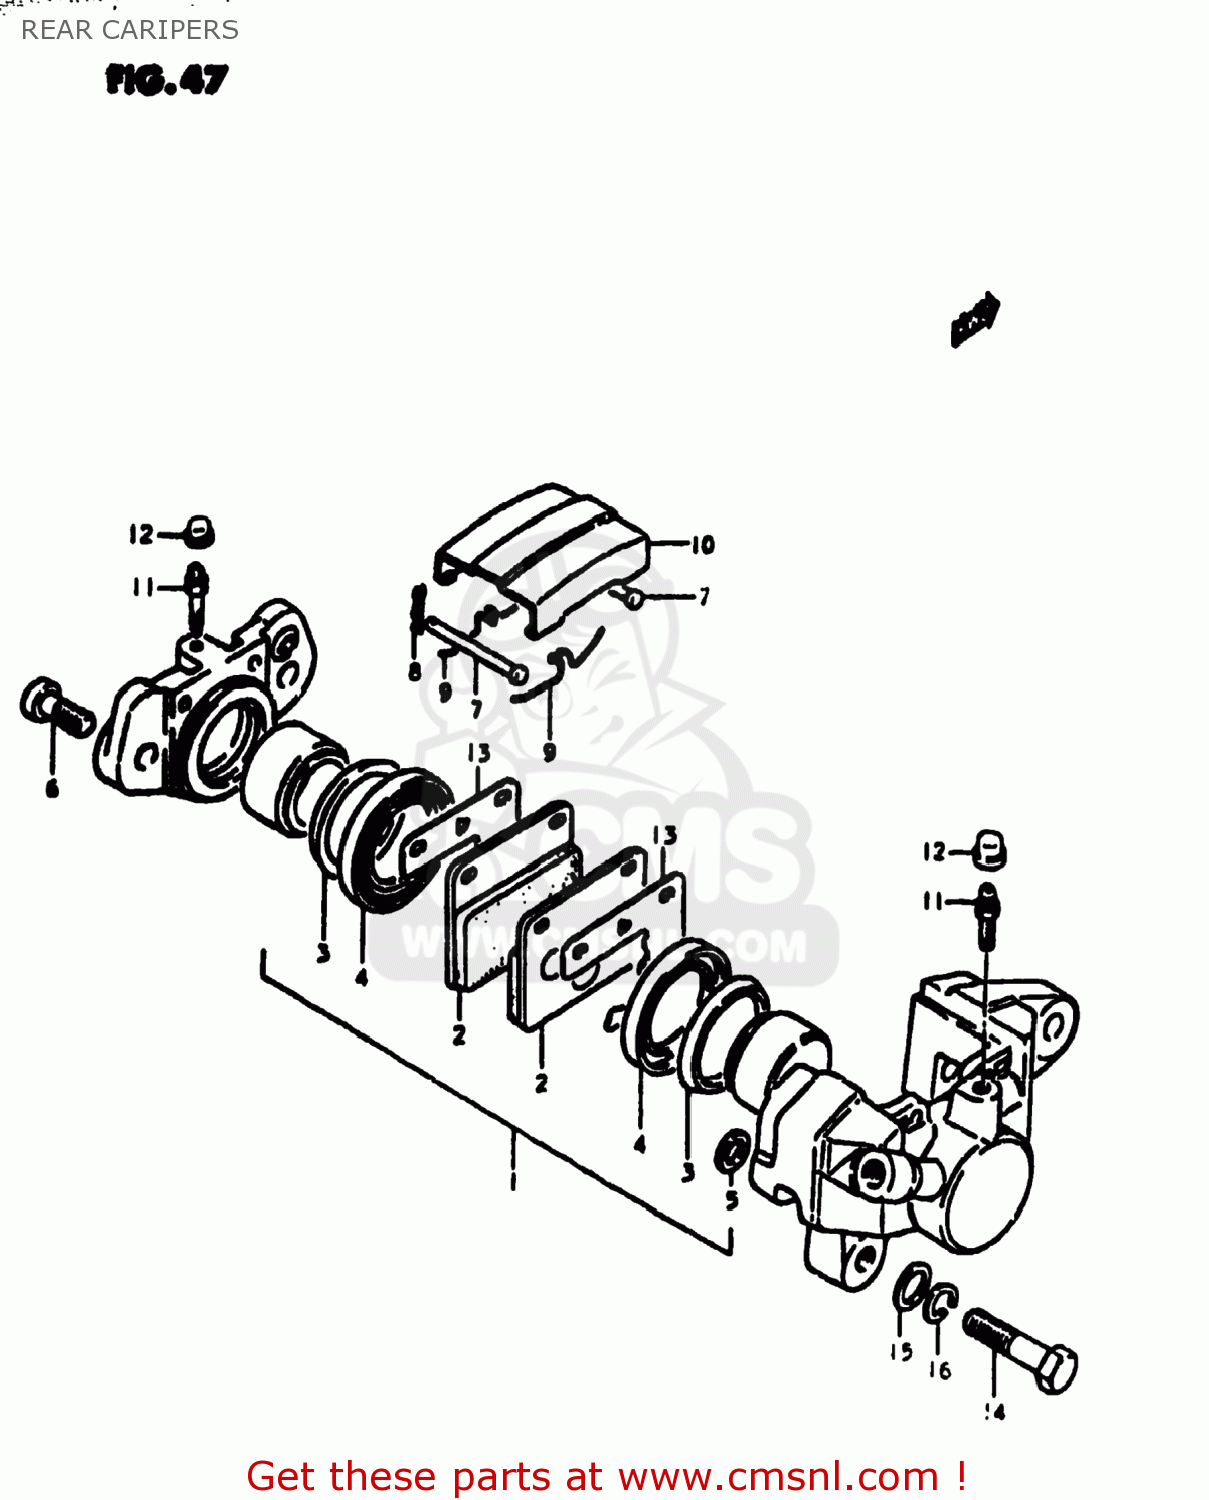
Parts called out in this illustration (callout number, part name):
1	PISTON SET
2	PAD,BRAKE
3	SEAL,PISTON
4	BOOT,PISTON
5	SEAL,PISTON
6	BOLT,HOUSING
7	PIN,PAD
8	CLIP,PAD PIN
9	SPRING
10	COVER,DUST
11	BLEEDER
12	CAP,BREATHER
13	SHIM,RR CALIPER
14	BOLT 10X34
15	WASHER
16	LOCK WASHER
